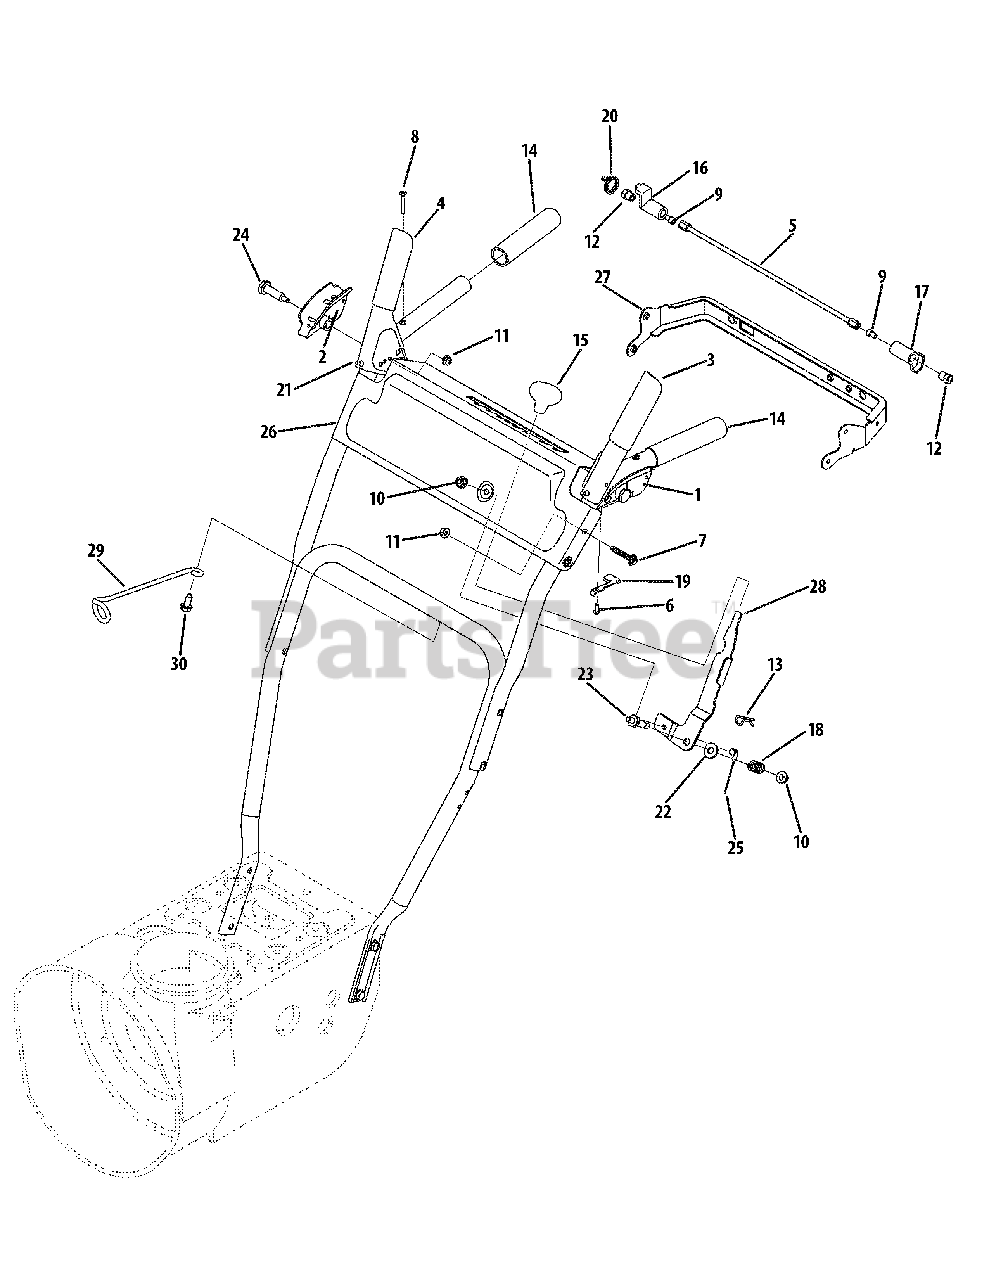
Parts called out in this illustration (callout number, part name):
1	Clutch Lock Handle Assembly, LH
2	Clutch Lock Handle Assembly, RH
3	Engagement Assembly, LH
4	Engagement Assembly, RH
5	Clutch Pivot Lock Rod Assembly
6	Hex Washer Screw, 8-16 x .50
7	Hex Washer Screw, 1/4-20 x 1.625
7	Hex Screw, 1/4-20 x 1.50
8	Machine Screw, 1/4-20 x .50
9	Socket Head Cap Screw, 1/4-20 x .50
10	Flange Lock Nut, 5/16-18
11	Flange Lock Nut, 1/4-20
12	Hex Nut, 1/4-20
13	Click Pin, .092 x 1.64
14	Grip, 1.0 ID x 5.0 LG
15	Shift Knob
16	Lock Plate
17	Clutch Lock Cam
18	Compression Spring, .39 x .60 x .88
19	Clutch Lock Spring
20	Torsion Spring, 0.8156 ID x .3038
21	Rubber Bumper, .62 OD x .22 Thick
22	Flat Washer, .385 x .870 x .092
23	Shoulder Bolt, 5/16-18 x .905
24	Shoulder Screw, .437 x 1.345 x 1/4-20
25	Speed Selector Cable
29	Cable Guide
30	Hex Washer Screw, 5/16-18 x .750
